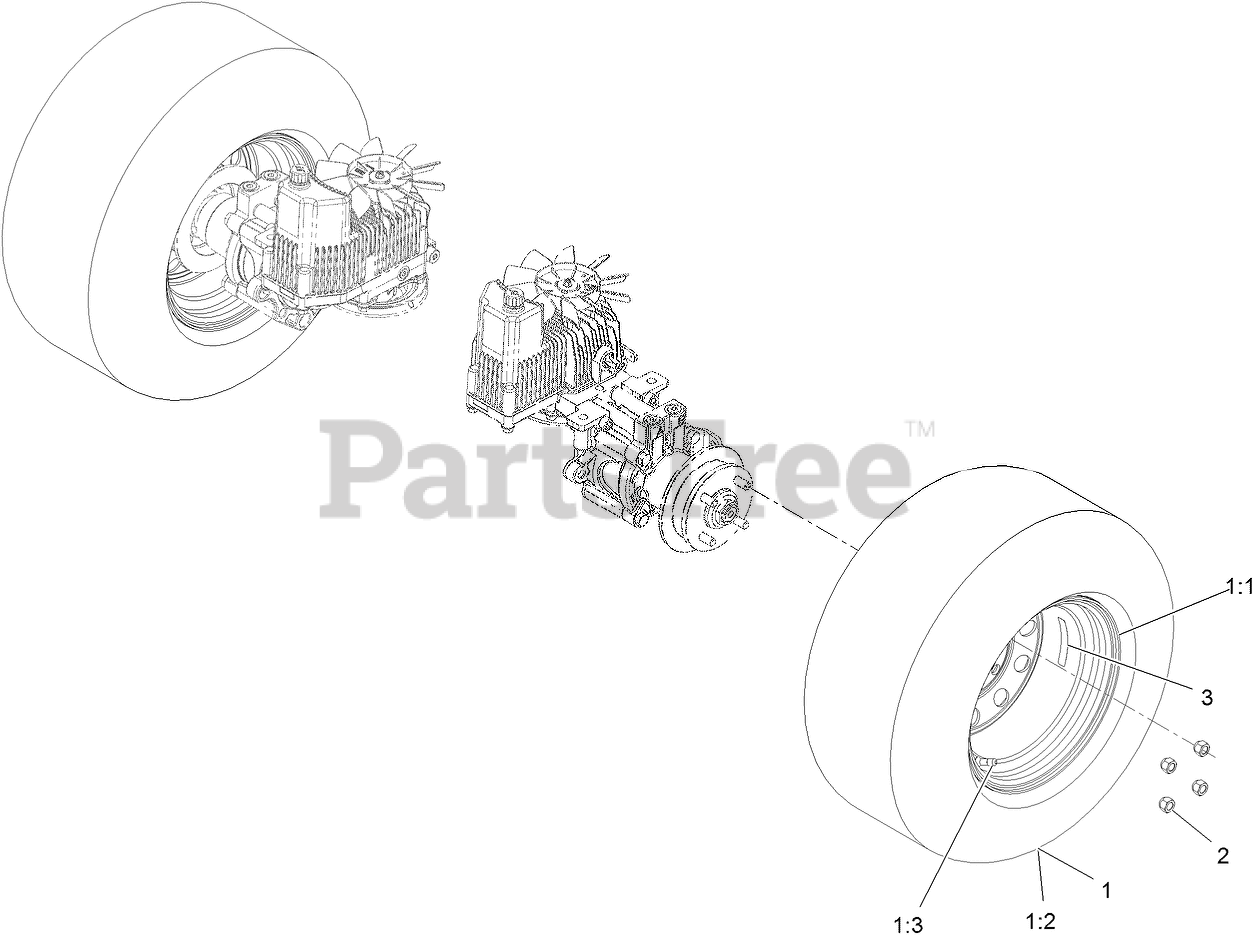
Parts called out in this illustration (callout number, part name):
1	WHEEL AND TIRE ASM
1:3	Stem-Valve
2	NUT-LUG
3	Decal-Wheel Hub
